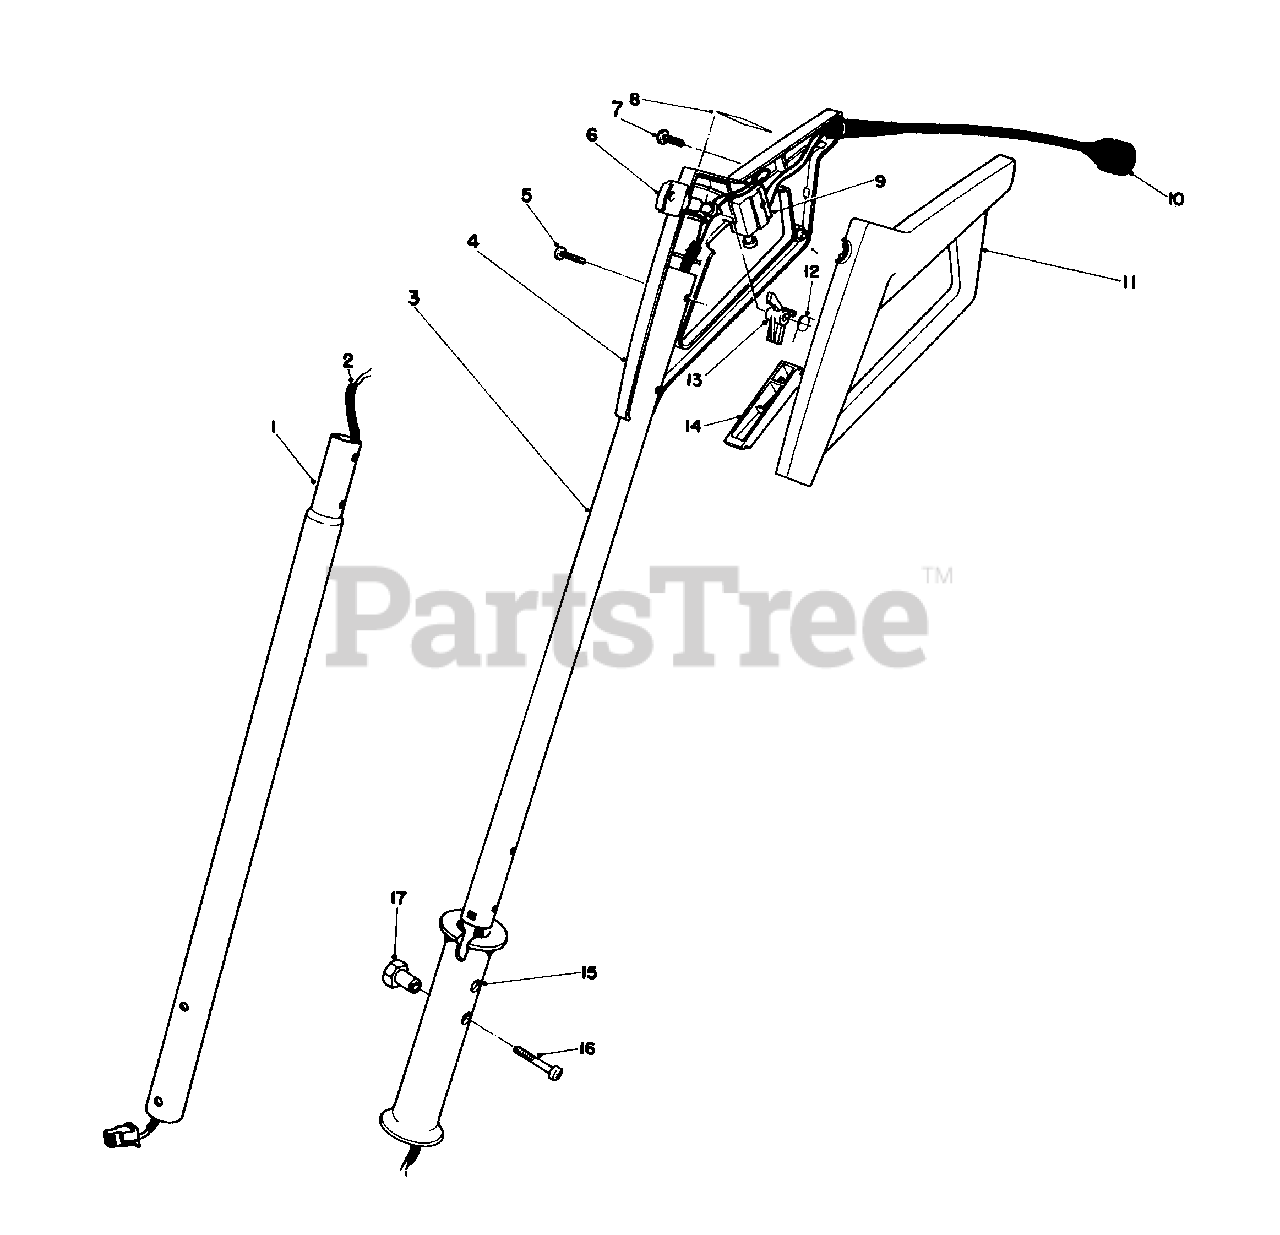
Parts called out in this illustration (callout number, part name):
1	Tube-Lower Handle
2	Wire Harness
3	Tube-Upper Handle
4	Grip-Control R.H.
5	Screw, Pan Head
7	Screw, Pan Head
8	Decal-Control Grip
10	Cord-Supply
11	Grip-Control, L.H.
14	Switch Bar
15	Grip-Handle
16	Screw-Pan Head Special
17	Nut-Hex Special
